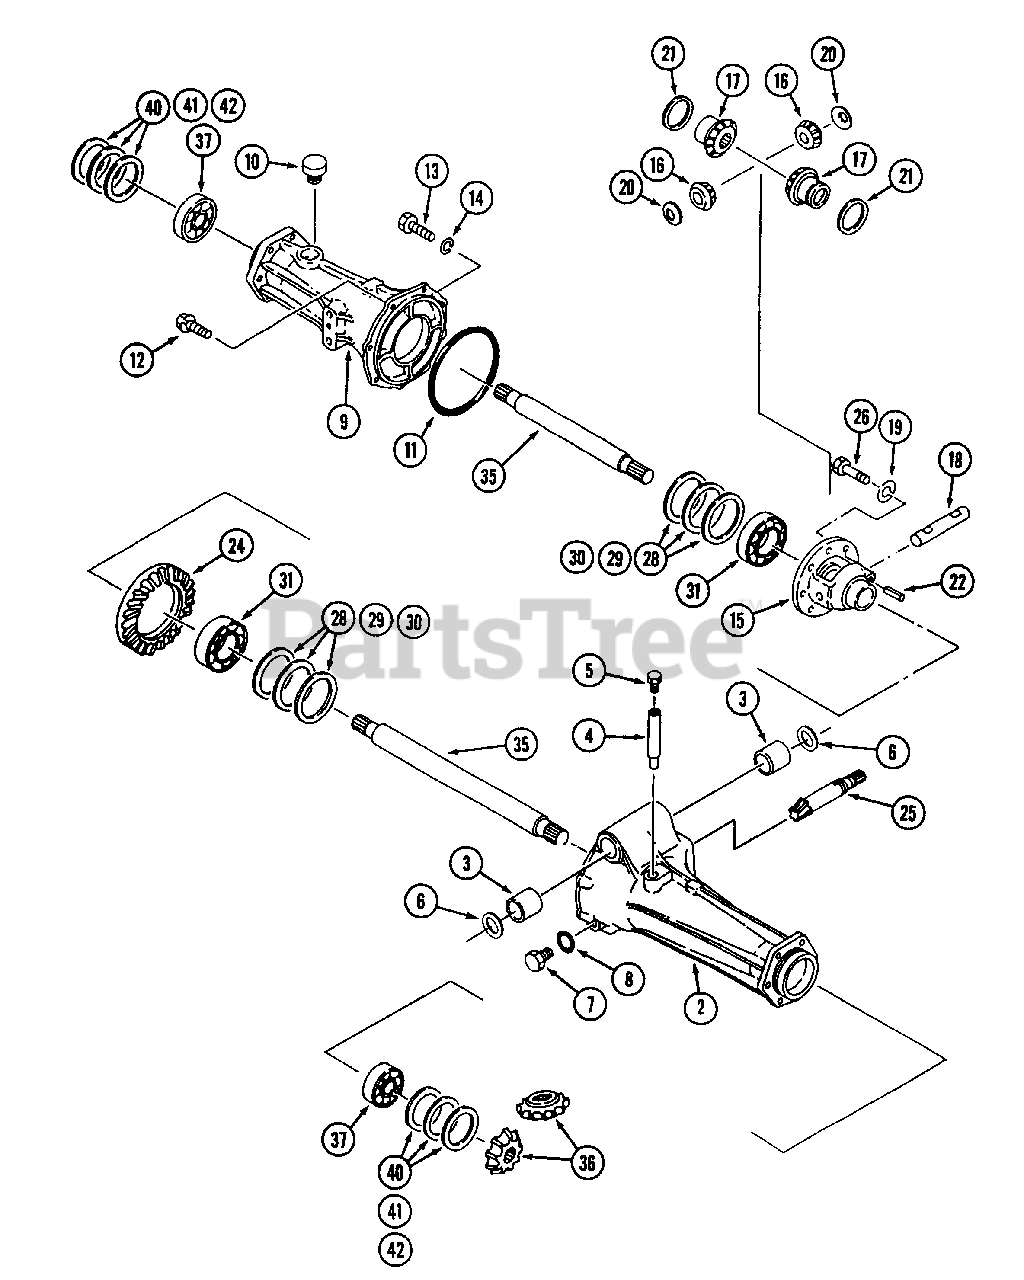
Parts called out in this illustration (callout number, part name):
2	Housing, Axle A
6	O-Ring
8	Washer, Seal
9	Housing B, Center
18	Shaft, Pinion
20	Washer, Thrust
21	Washer, Thrust
24	Gear, Ring
25	Shaft, Pinion
